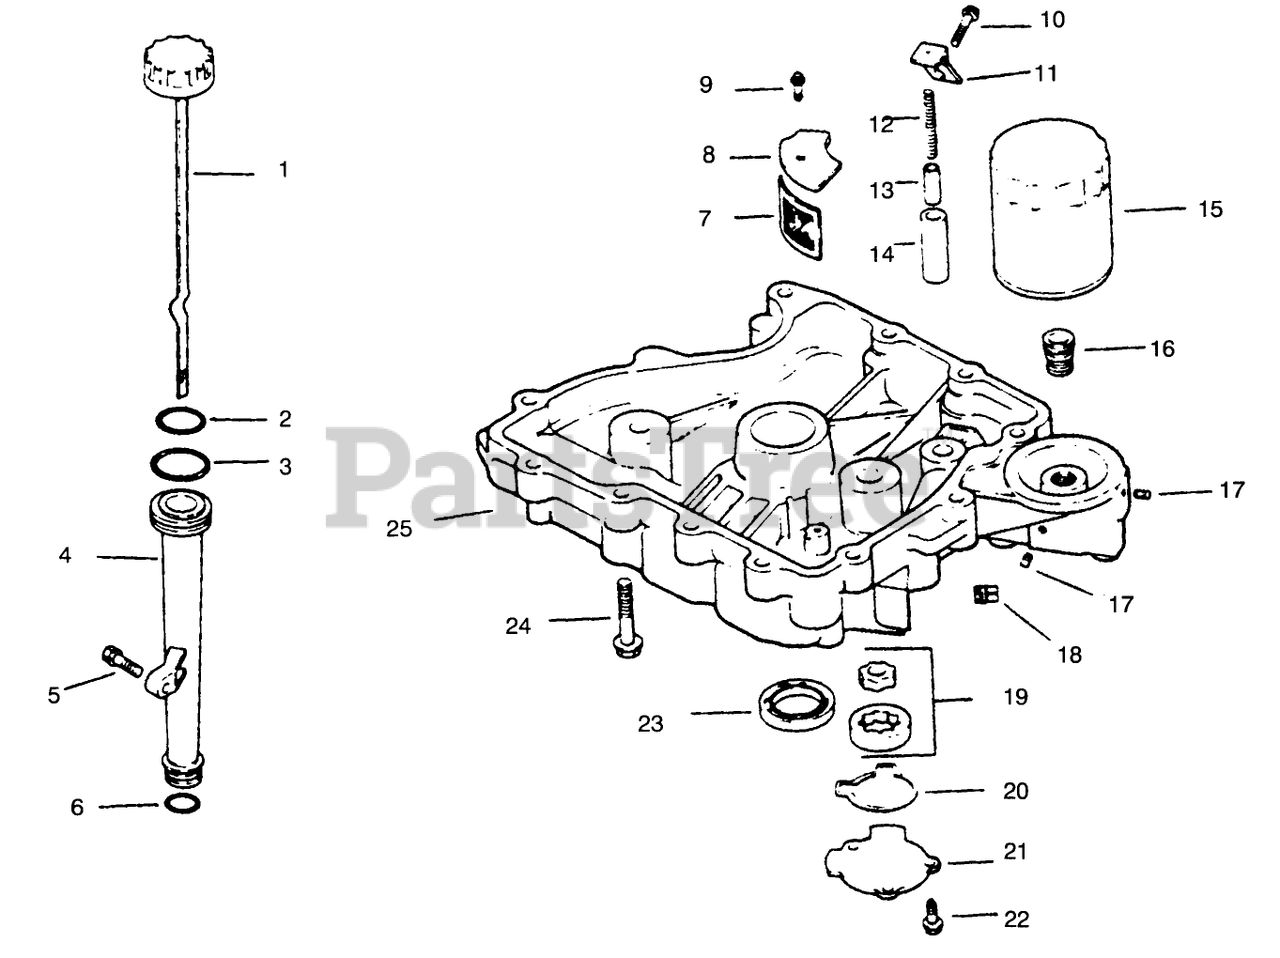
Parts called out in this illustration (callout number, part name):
1	Dipstick INC 2-3
2	"O"Ring
3	"O"Ring
4	Tube-Oil Fill
5	Screw
6	"O"Ring
7	Screen-Oil
8	Cover-Oil Screen
9	Screw
10	Screw
11	Bracket-Oil Pump Relief
12	Spring-Oil Relief Valve
13	Piston-Oil Relief Valve
14	Body-Oil Relief Valve
15	Filter-Oil
16	Adapter-Oil Filter
17	Plug-SH 1/8
18	Plug
19	Pump-Oil
20	"O"Ring-Pump Cover
21	Cover-Oil Pump
22	Screw
23	Seal-Crankshaft
25	Pan-Oil
